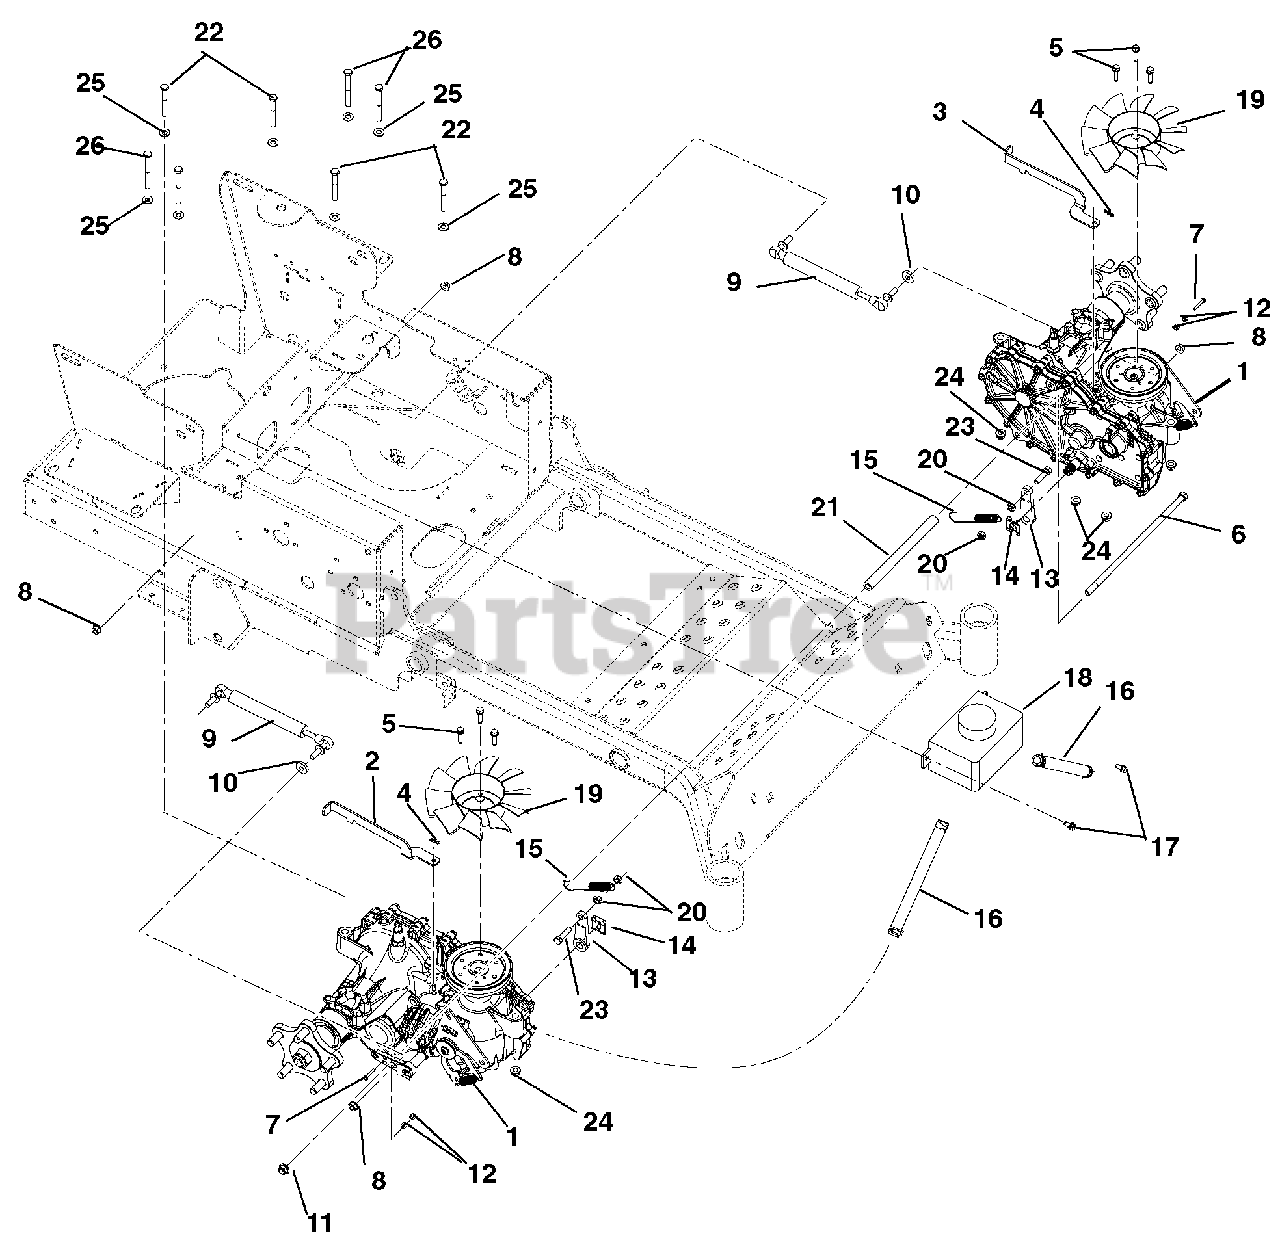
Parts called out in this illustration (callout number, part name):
1	Transaxle, 2800 Series- Left Hand
1	Transaxle, 2800 Series- Right Hand
2	Right Hand Dump Valve Lever- Black
3	Left Hand Dump Valve Lever- Black
4	Pin-Hair-Internal .06 x .18 x .77
5	Screw, Tapping .25-20 x 1.00 Hex Washer Head Thread
6	Bolt, Hex .38-16 x 11.00 Grade 5
7	Screw, Machine 8-32 x 1.00 Hex Washer Head
8	Nut, M8-1.25 WHIZ Lock
10	Washer, Flat-Steel .38 x .87 x .179
11	Nut, .38-16 Nyloc Flange
12	Nut, Locking-Nylon 8-32
13	Arm, Brake
14	Clip, Brake Arm
15	Spring, Tension .056 x .60 x 4.60 LG
16	Assembly, Hydro Overflow Tank Hose
17	Screw, Tapping .25-20 x .50 Hex Washer Head Thread
18	Tank, Expansion
19	Fan, Cooling
20	Nut, Locking-Center .31-18
21	Spacer, .38 ID x 5/8 OD x 7.72
22	Bolt, Hex .31-18 x 2.50 Grade 5
23	Bolt, Hex .31-18 x 1.25 Grade 5
24	Nut, Nyloc Flange .312-18
25	Washer, Flat-Steel .344 x .688 x .065
26	Bolt, Hex .31-18 x 3.00 Grade 5
